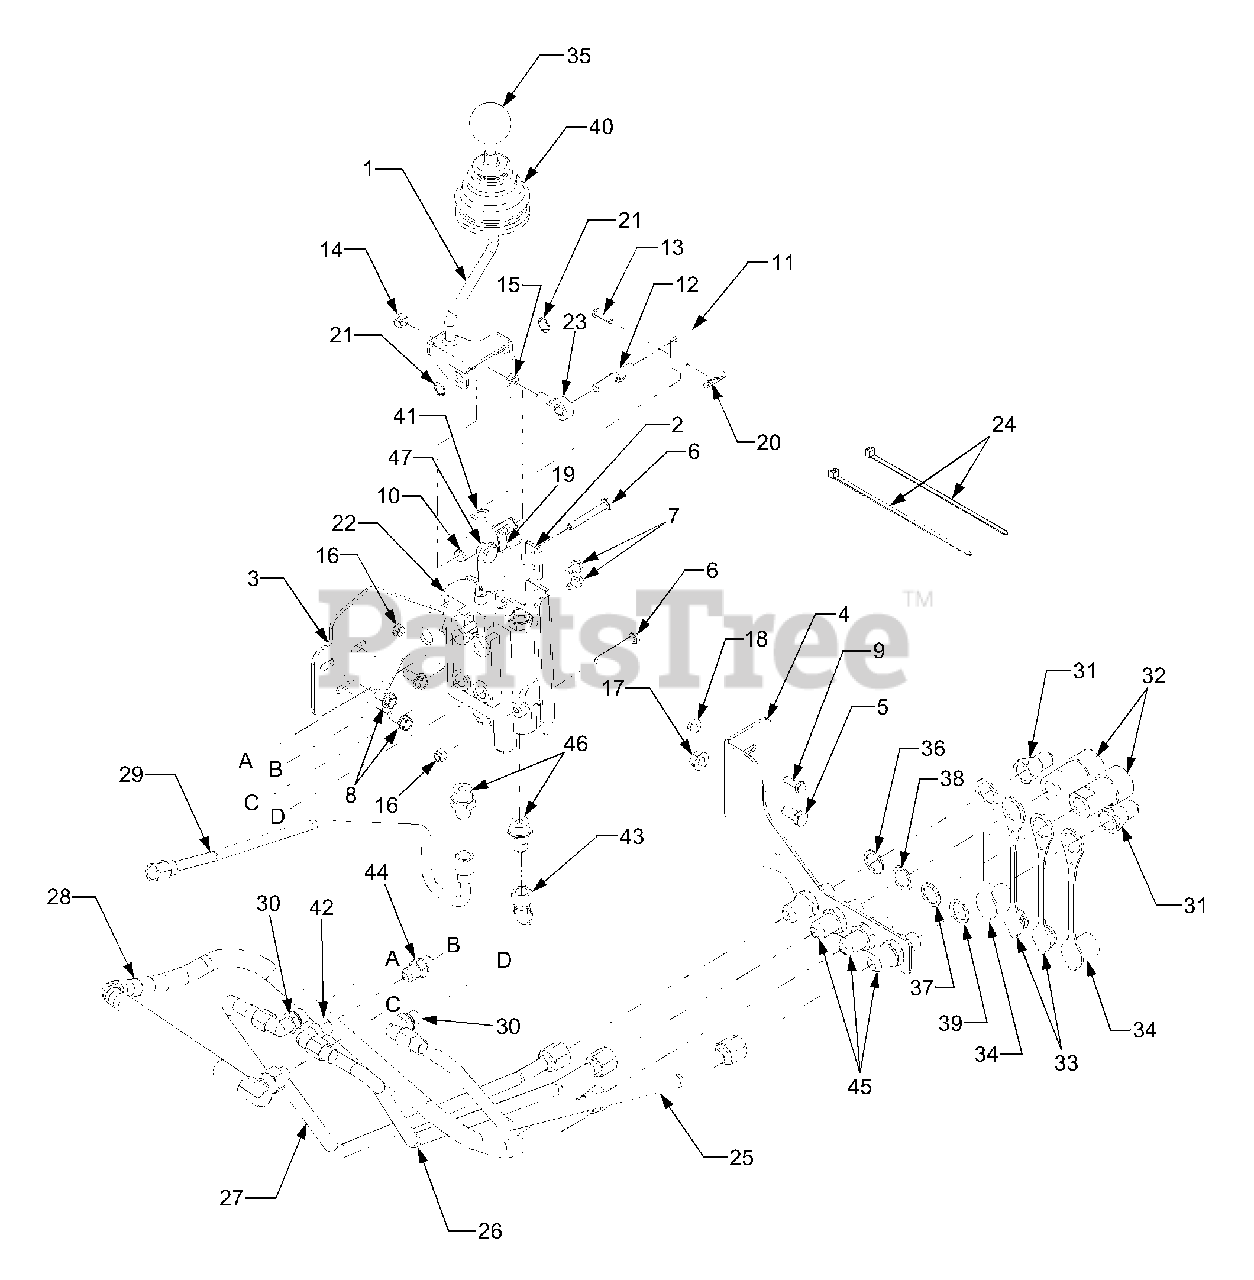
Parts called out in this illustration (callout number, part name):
1	Handle Assembly, Valve
2	Bracket Assembly,Pivot
3	Bracket, Valve Mounting
4	Bracket, Fitting Mount
5	Screw, Hex Cap, 3/8-16 x .75 GR5
6	Screw, Hex Cap , 1/4-20, 2.00, Gr5
7	Screw, Hex Wash. Hd. Tapp 1/4-20 x .50
8	Screw, Hex Wash. Hd. Tapp 5/16-18 x .75
9	Screw, Hex Cap 1/4-20 x .75 GR5
10	Shaft, Valve Pivot
11	Link, Valve Spool
12	Stud, Ball Joint Pivot
13	Pin, Clevis, .199 x .8125
14	Nut, Hex Lock, 5/16-24
15	Nut, Jam, 5/16-24, Gr2
16	Nut, Hex Nylon Lock, 1/4-20, Gr8
17	Nut, Hex Flange Lock, 3/8-16
18	Nut, Hex Flange Lock, 1/4-20
19	Link, Chain
20	Pin, Internal Cotter
21	Ring, Snap
22	Valve, Control
23	Ball Joint, .3125 Id x 5/16-24
24	Tie, Cable
25	Tube, Hydraulic - Bucket Return
26	Tube, Hydraulic - Bucket Lift
27	Tube, Hydraulic - Boom Lift
28	Hose, Hydraulic - Boom Return
29	Tube, Hydraulic - Valve Return
30	Fitting, 90° 6-6 Orb
31	Coupling, Male Hydraulic, 3/8-18
32	Coupling, Female Hydr. 3/8-18
33	Plug, Hydraulic Coupler - Male
34	Plug, Hydraulic Coupler - Female
35	Knob, 1.625 Dia x 3/8-16 Thd
36	Washer, Indicator - Red
37	Washer, Indicator - Yellow
38	Washer, Indicator - Green
39	Washer, Indicator - Blue
40	Joystick Boot
41	Washer, Spring, .45 x .75 x .015
42	Fitting, 90 Degree, 6 -6 Swivel
43	Fitting, 45 Degree, 6 -6 Swivel
44	Fitting, Straight - 6 Orb
45	Fitting, Bulkhead 3/4-16 x 3/8-18
46	Fitting, Straight - 6 -8 Orb
47	Spacer, .34 ID x .5 OD x .31
